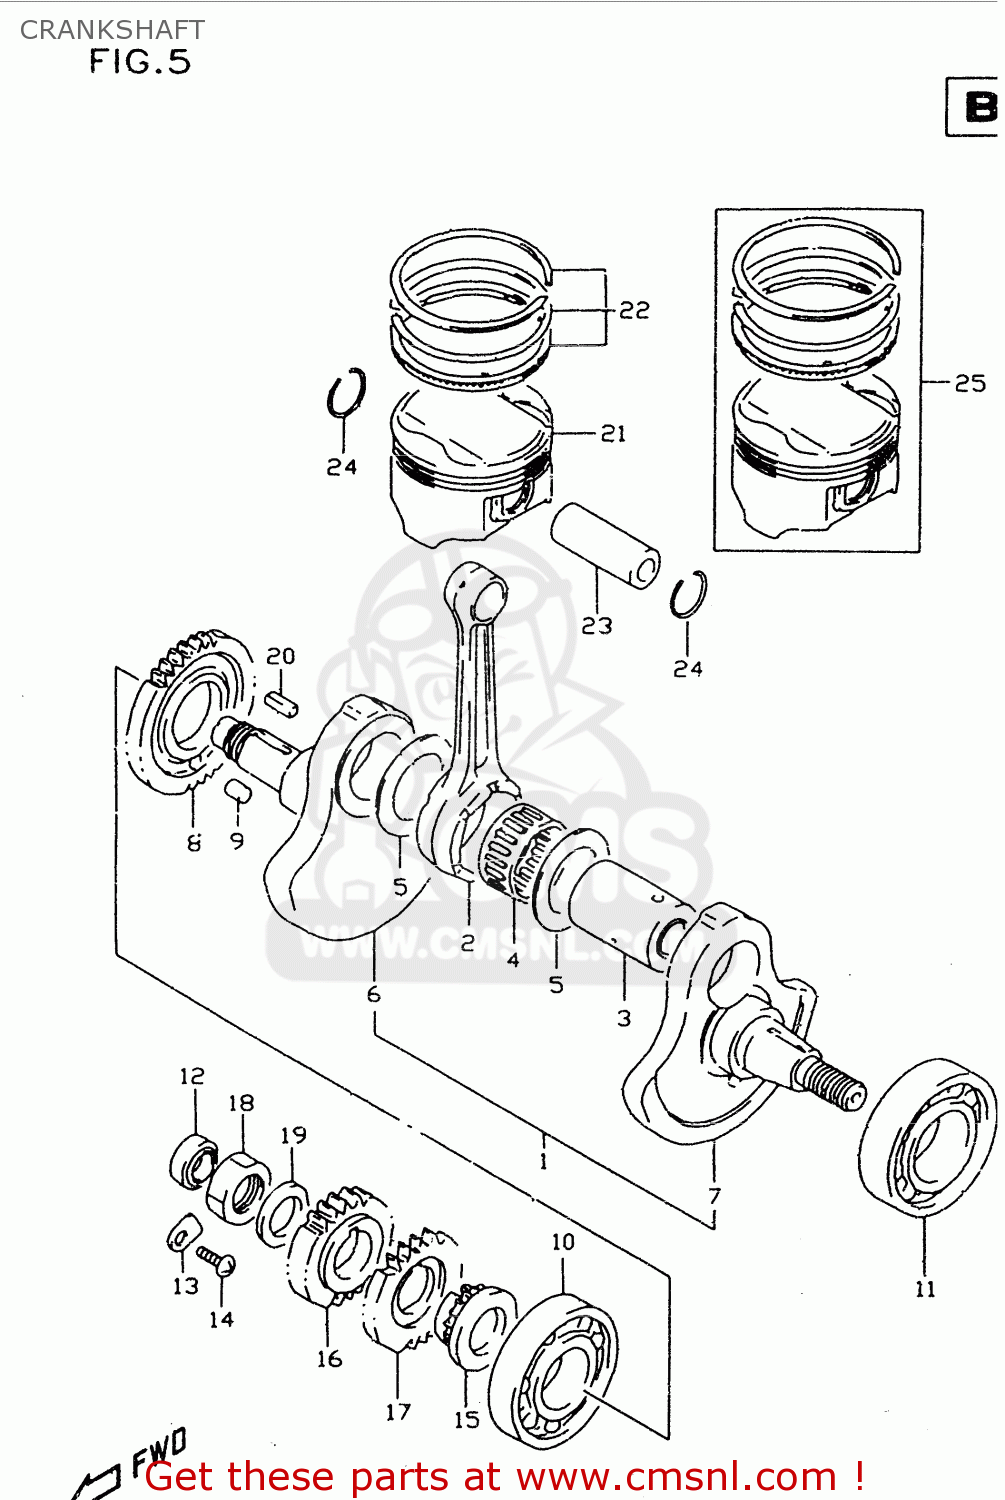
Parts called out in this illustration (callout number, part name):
1	CRANKSHAFT ASSY
2	ROD,CONNECTING
3	PIN COMP,CRANK
4	BEARING(34X43X22)
5	WASHER(34X52X1)
6	CRANKSHAFT,R
7	CRANKSHAFT,L
8	GEAR,CRANK BAL DRIVE(NT:37)
9	PIN
10	BEARING(30X72X19)
11	BEARING(35X72X17)
12	SEAL,OIL(14X24X6)
13	RETAINER,BEARING
14	SCREW
15	SPROCKET,CAM CHAIN DRIVE
16	GEAR,PRIMARY DRIVE
17	GEAR,OIL PUMP DRIVE (NT
18	NUT
19	WASHER
20	KEY
21	PISTON
22	RING SET,PISTON
23	PIN,PISTON
24	CIRCLIP,PISTON PIN
25	PISTON SET(OS:0.5)
